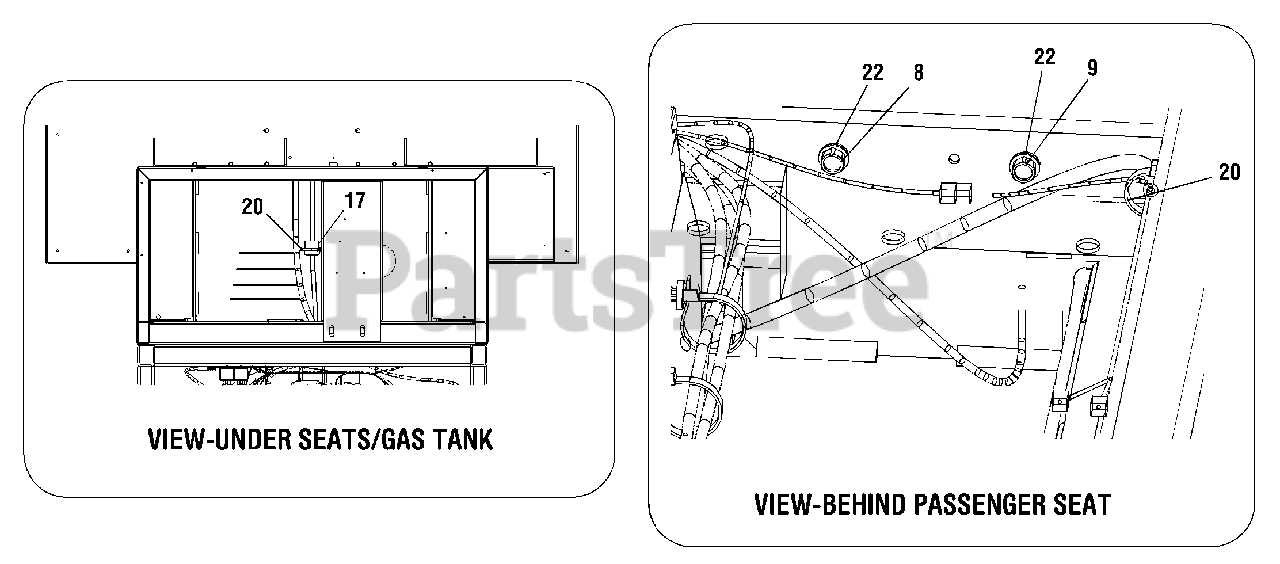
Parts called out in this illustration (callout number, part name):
8	Screw, Self-tapping, 1/4-20 x 1.000
9	Screw, #10-24 x 0.75
17	Control, Reverse
20	Cable Tie, .19 x 8.39 Tree Mount
22	Lock Washer, 1/4
